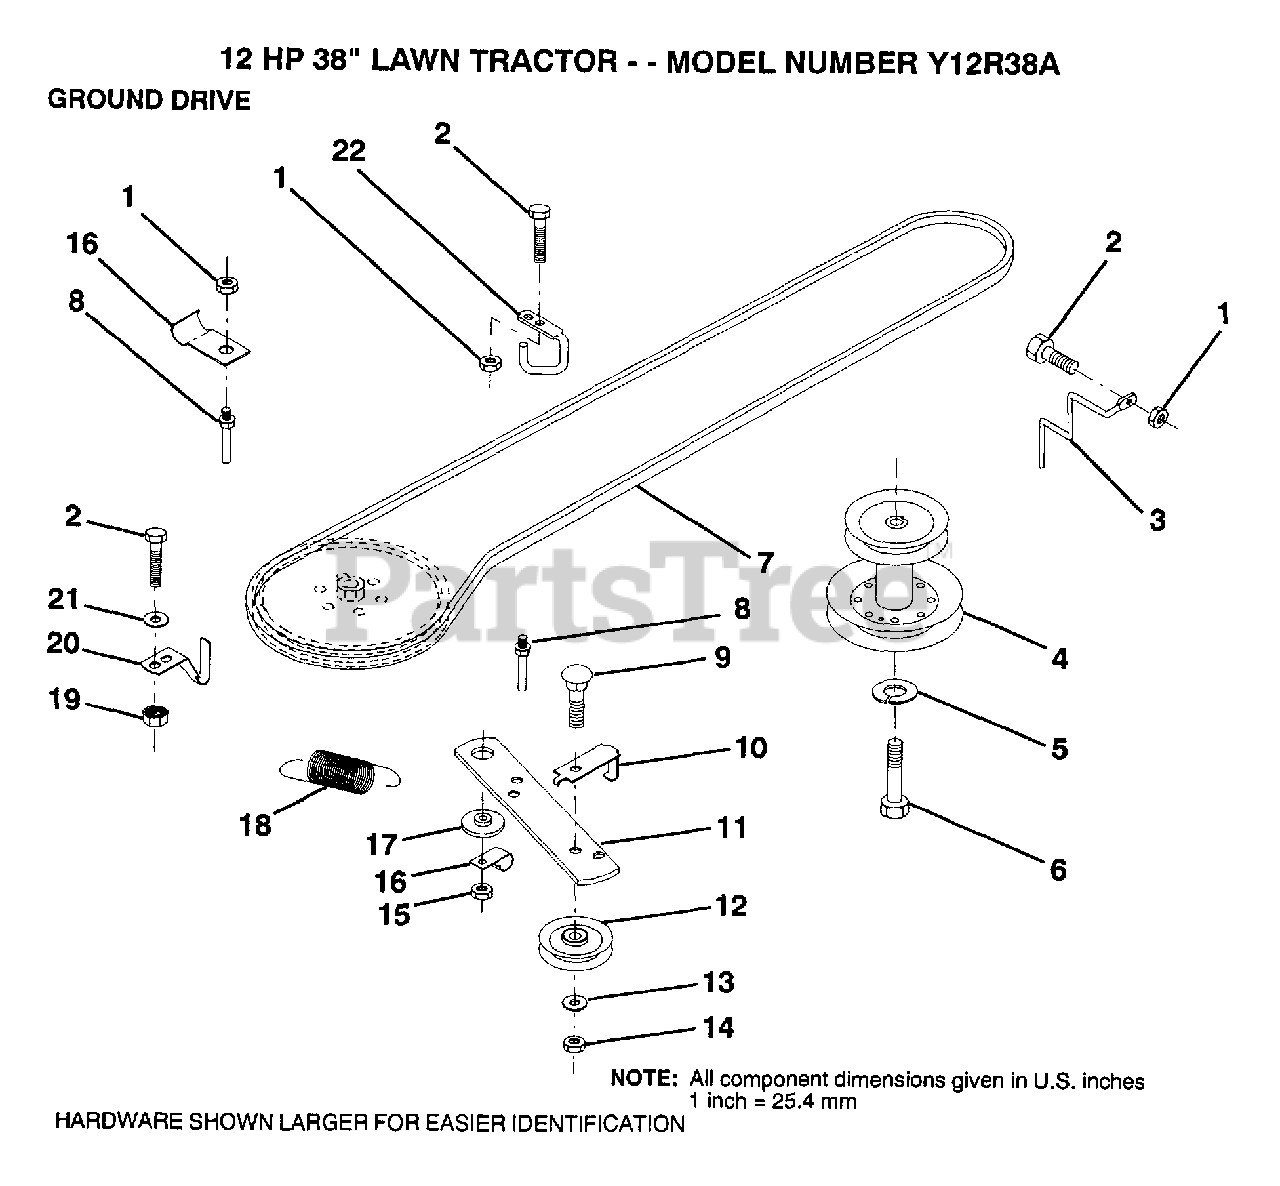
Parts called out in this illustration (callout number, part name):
2	BOLT
3	KEEPER MWR DR BLT
5	LOCKWASHER
6	BOLT
7	BELT
8	"KEEPER,DRIVE BELT"
9	BOLT
10	"KEEP,IDLER DR BEL"
13	WASHER
14	LOCKNUT
16	"CLIP,INSULATOR"
17	SPACER RETAINER
20	"KEEPER,DR BELT "
21	WASHER
22	"KEEPER,FRA DR BEL"
